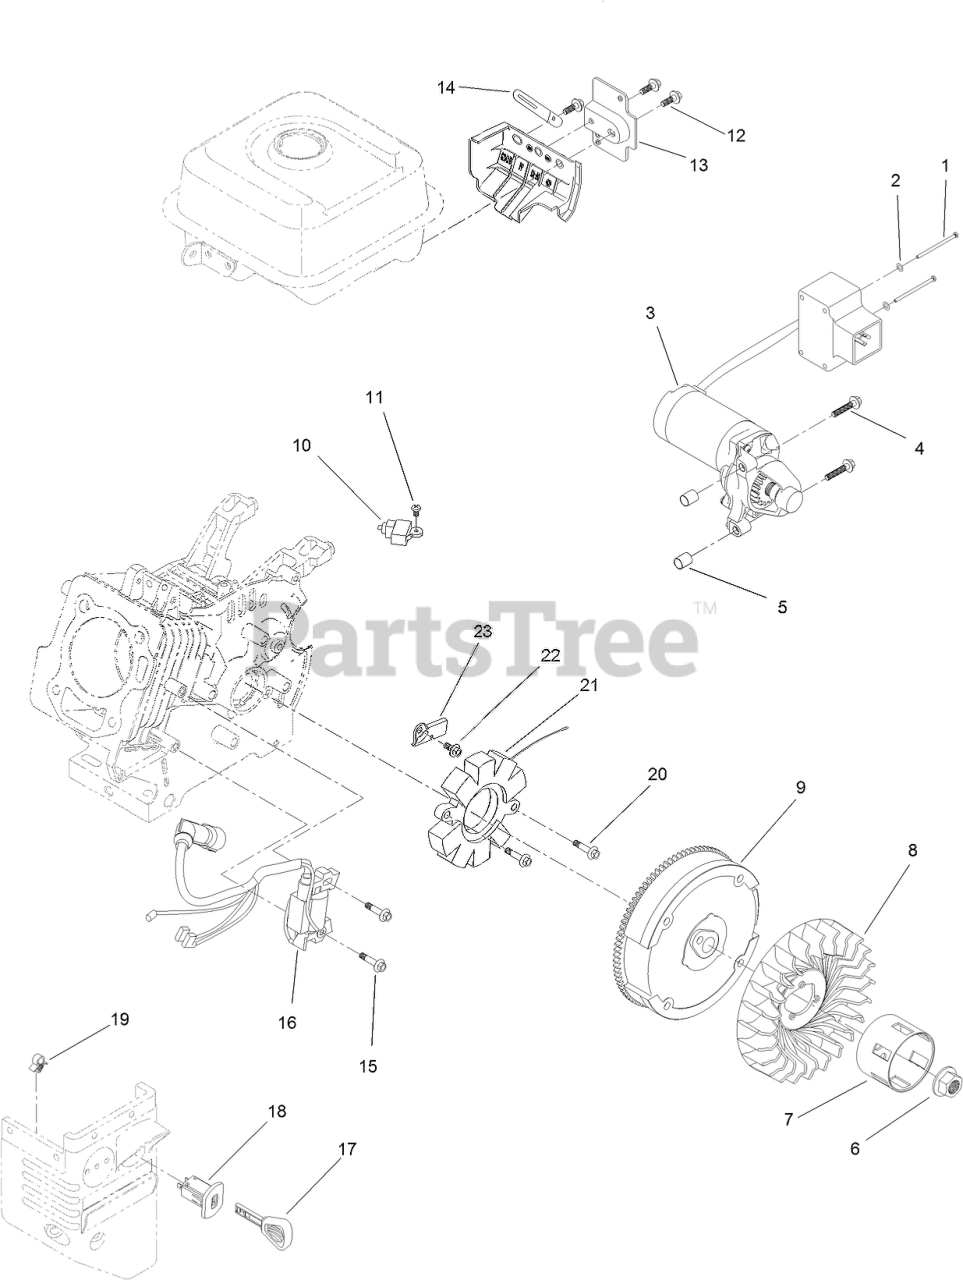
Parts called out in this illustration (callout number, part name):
1	SCREW-BHP
2	WASHER-PLAIN
3	MOTOR-STARTER
4	SCREW-FLANGE
5	PIN-DOWEL
6	NUT-FLANGE
7	CUP-STARTER
8	FAN-COOLING
9	FLYWHEEL ASM
10	SWITCH-KILL, ENGINE
11	SCREW-PPH
12	SCREW-HHF
13	BRACKET-SWITCHBOX, STARTER
14	CLIP-HARNESS, WIRE
15	SCREW-HHF
16	IGNITION COIL ASM
18	SWITCH-KEY
20	SCREW-HHF
21	ALTERNATOR
22	SCREW-HHF
23	CLAMP-WIRE, CHARGE
